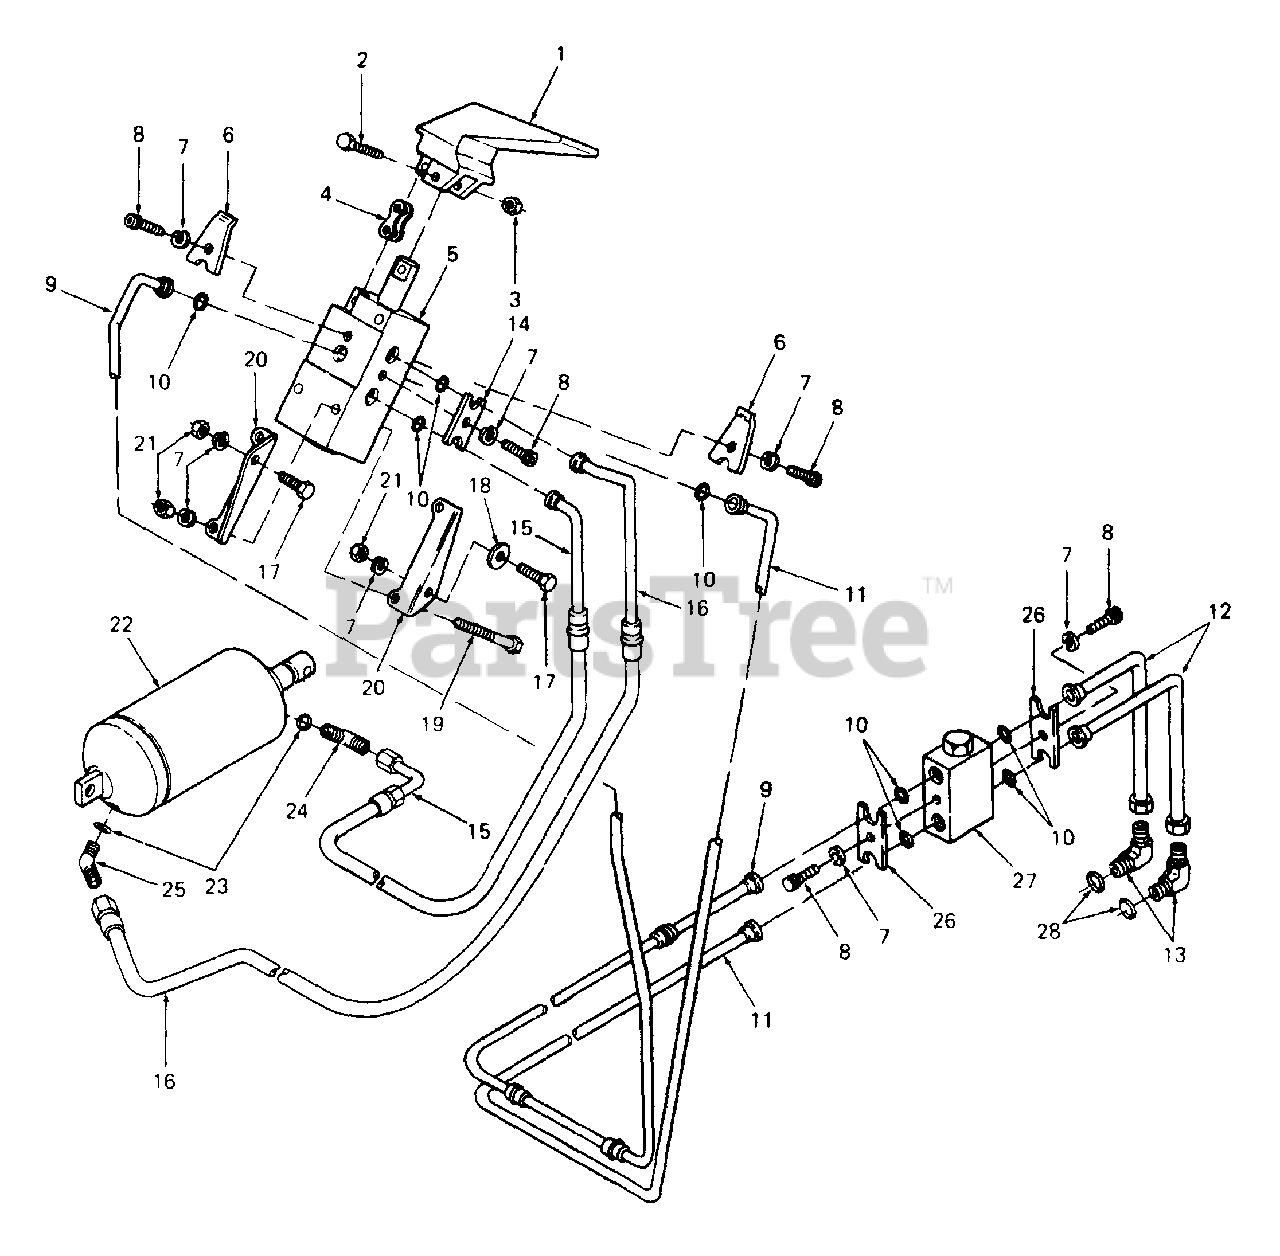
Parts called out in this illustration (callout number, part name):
1	Handle, Valve
2	Screw, Hex Cap, #10-24 X 1.0 Lg
3	Nut, Hex Center Lock, #10-24
4	Link, Chain
5	Valve, Lift
6	Clamp, Single
7	Washer, Lock, 1/4
8	Screw, Socket Hd Cap, 1/4-20 X .62 Lg GR8
9	Tube Assy, Return
10	O-Ring, .301 X .070 Dia
11	Tube Assy, Pressure
12	Tube Assy, Adapter
13	Elbow, Tube, 90 Degree
14	Clamp, Double
15	Hose, Cylinder - Contracting
16	Hose, Cylinder - Extending
17	Screw, Hex Cap, 1/4-20 X .62 Lg GR5
18	Washer, Bell, .265 X .75 X .062 Thk
19	Screw, Hex Cap, 1/4-20 X 2.25 Lg
20	Bracket, Valve Mtg
21	Nut, Hex, 1/4-20 GR5
22	Cylinder, Hydraulic
23	O-Ring, 1/4 OD Tube
24	Elbow, 90 Degree w/O-Ring
25	Elbow, 45 Degree w/O-Ring
26	Clamp, Valve Side
27	Valve, Relief
28	O-Ring, 3/8 OD Tube
